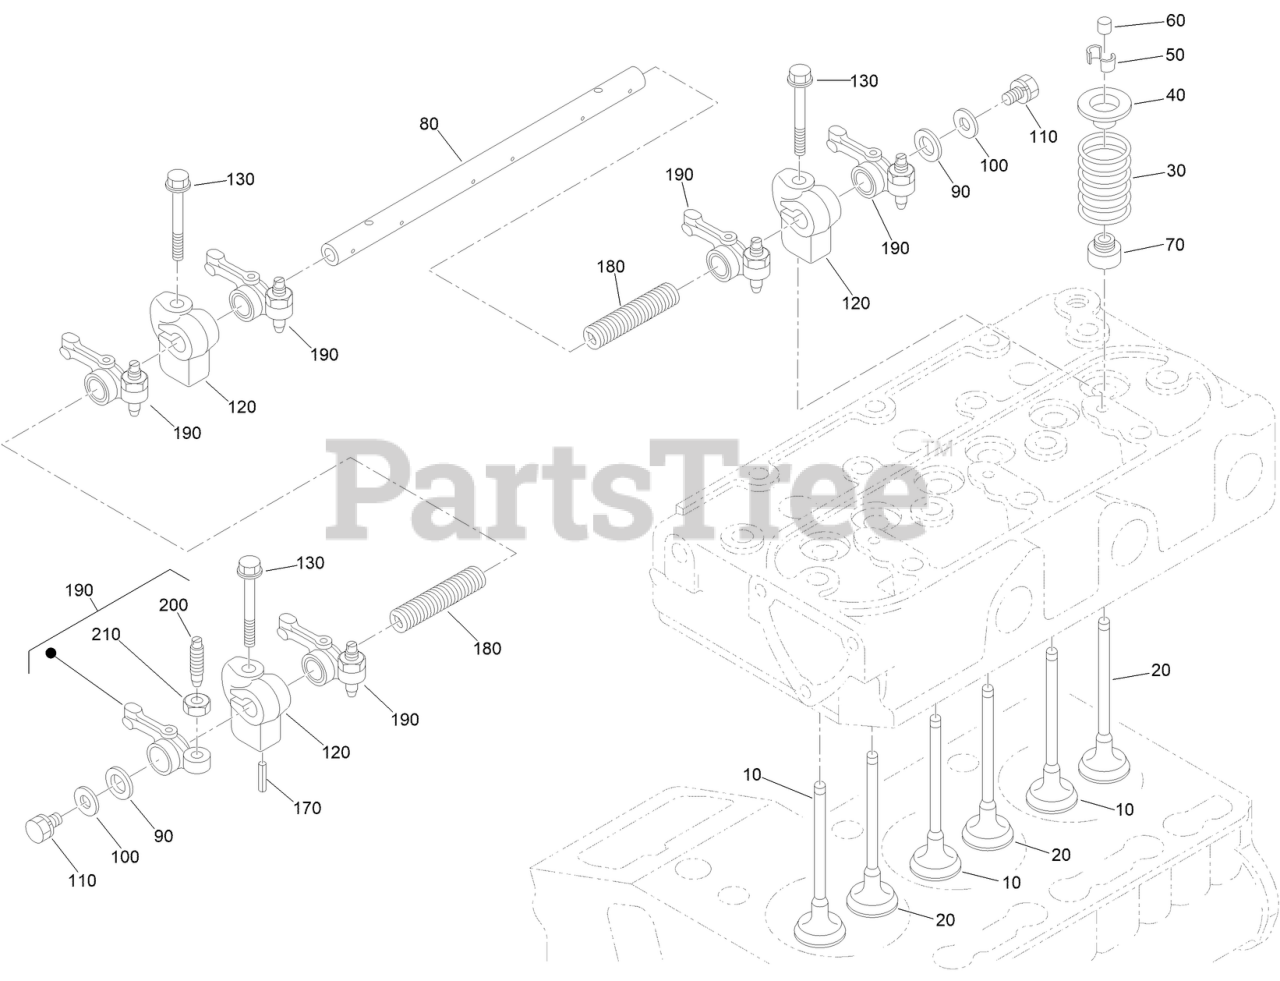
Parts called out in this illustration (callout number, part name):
10	VALVE-INTAKE
20	VALVE-EXHAUST
30	SPRING-VALVE
40	RETAINER-SPRING, VALVE
50	COLLET-SPRING, VALVE
60	CAP-VALVE
70	SEAL-STEM, VALVE
80	SHAFT-ROCKER ARM
90	WASHER
100	WASHER-PLAIN
120	BRACKET-ARM, ROCKER
130	BOLT-FLANGE
170	PIN-SPRING
180	SPRING-ROCKER ARM
190	ROCKER ARM ASM
200	SCREW-ADJUSTING
